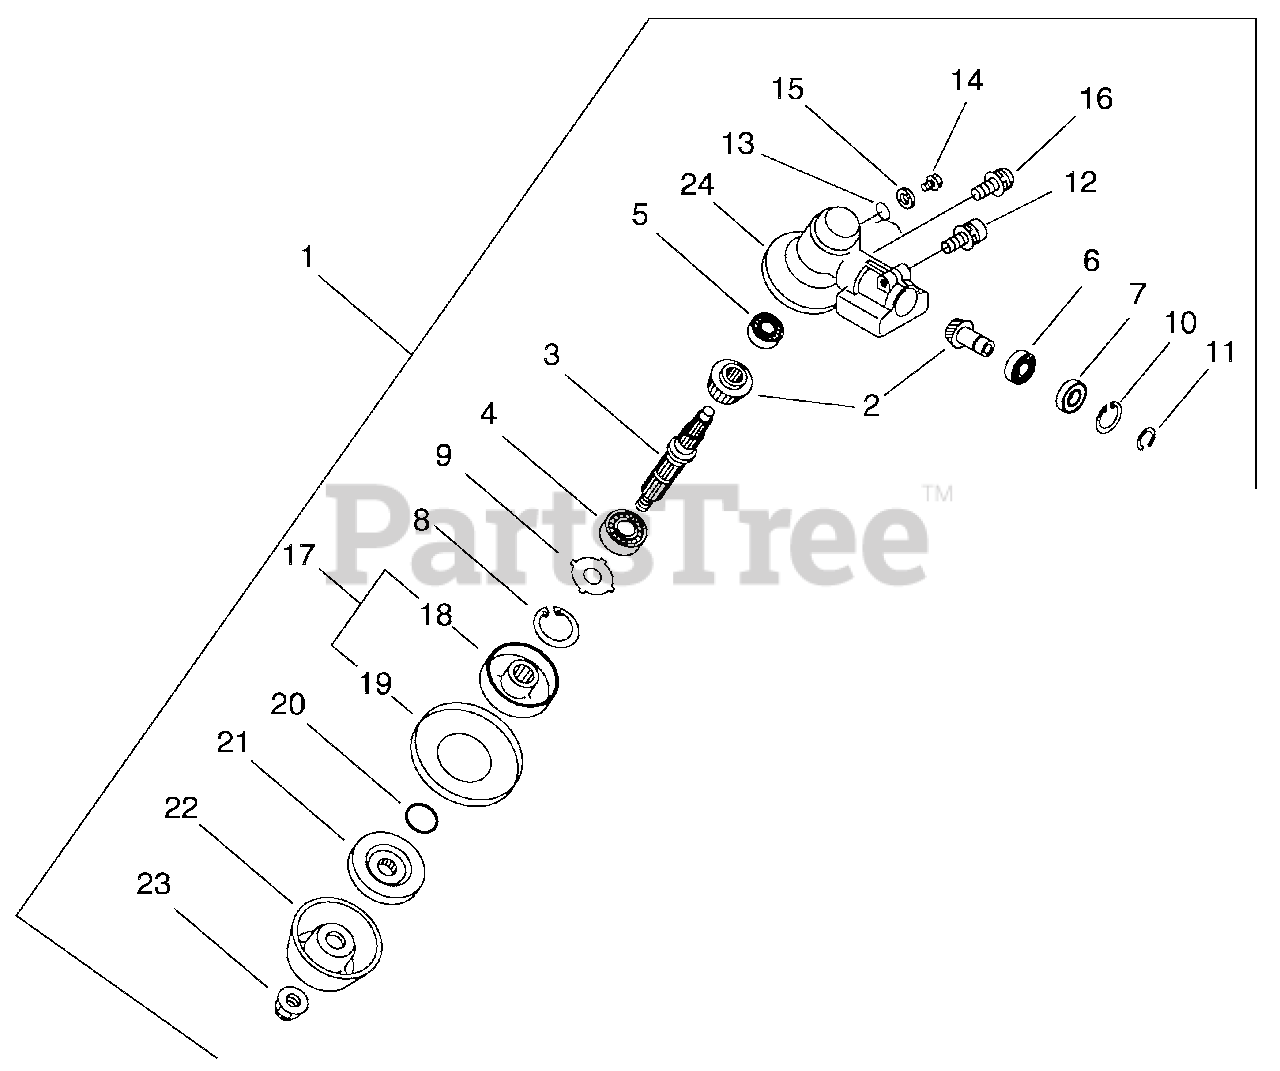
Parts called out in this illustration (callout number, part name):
1	GEAR CASE ASSY
3	SHAFT, GEAR
4	BEARING, BALL 6201
5	BEARING, BALL 626
6	BEARING, BALL 6900
7	BEARING, BALL 6900Z
8	RING, SNAP Ø32
10	RING, SNAP Ø22
11	RING, SNAP Ø10
13	SPRING, TORSION
14	BOLT M8×8
15	WASHER 8.5×18×0.8T
16	SCREW 5×10
17	RETAINER ASSY, BLADE
18	RETAINER, BLADE
19	PLATE, ADAPTOR - LOWER
20	O-RING 12 MM
21	PLATE, ADAPTOR - LOWER
23	NUT, LOCK 10 - NYLON INSERT
24	CASE, GEAR
